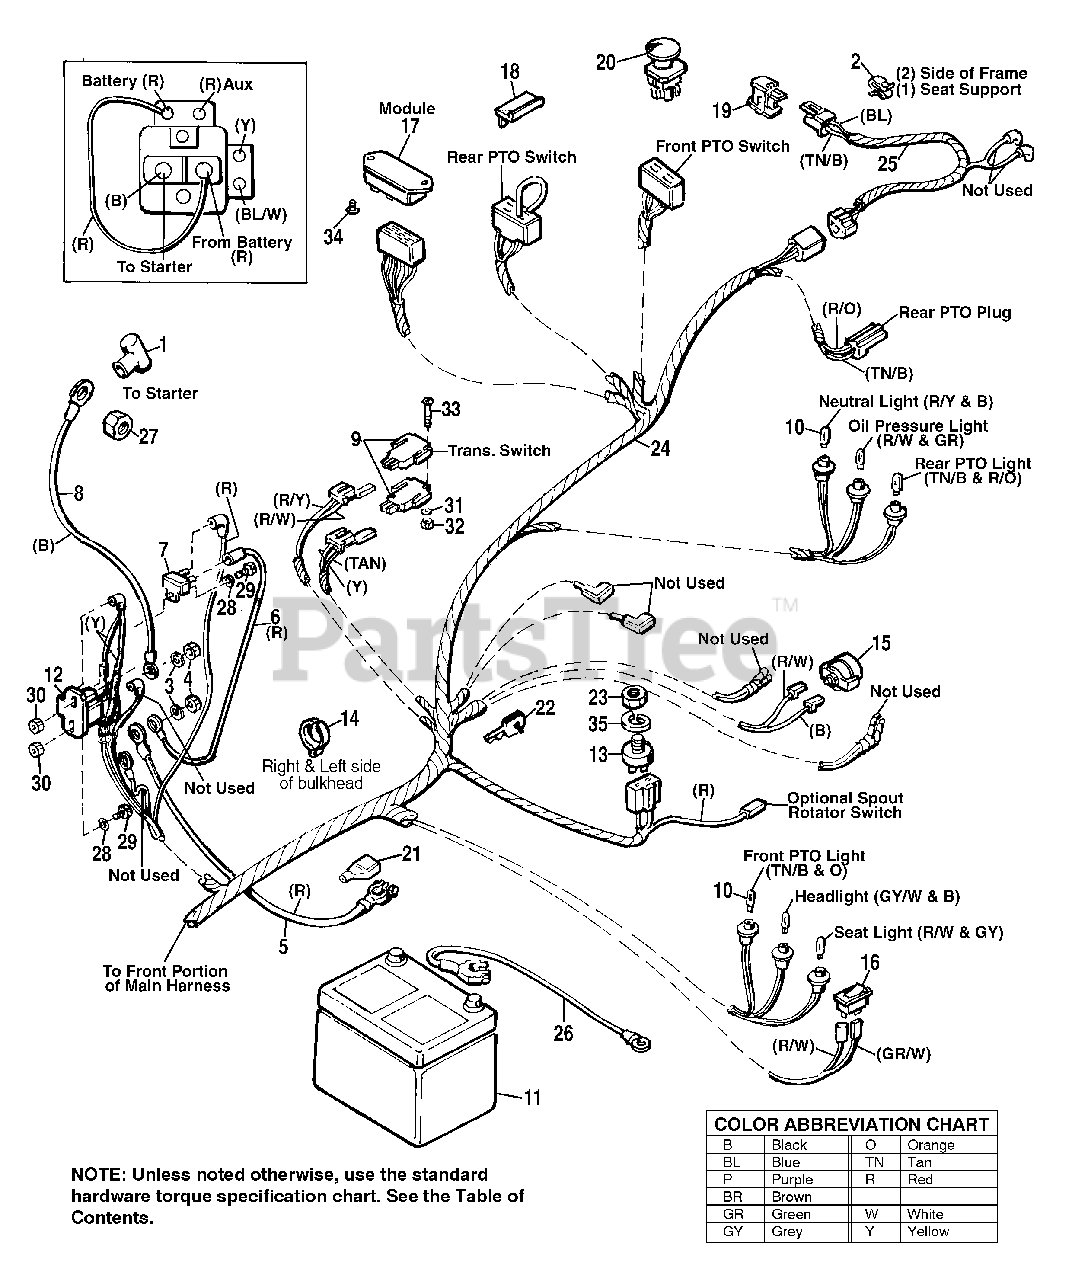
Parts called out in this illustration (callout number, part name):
1	COVER, Terminal
2	CLIP, Tinnerman
3	WASHER, 5/16, Zinc Plated
4	NUT, Hex, Jam, 5/16-24 Zinc Plated
5	CABLE (Battery to Solenoid)
6	WIRE, Solenoid to Circuit Breaker
7	BREAKER, Circuit
8	CABLE, Solenoid to Starter
9	SWITCH, Interlock (Under Dash) Shift Lever
10	LAMP, Indicator
11	BATTERY (400 AMP Cold Crank Rating)
12	SOLENOID (12 Volt DC)
13	IGNITION SWITCH KIT,
16	TOGGLE SWITCH, Headlight
17	INTERLOCK MODULE
19	SAFETY SWITCH (Seat), Operator Present
20	SWITCH ASSY., PTO
21	PROTECTOR, Battery (Red)
22	IGNITION KEY
23	NUT, Hex, Flange, 5/8
24	WIRING HARNESS (Main)
25	HARNESS, Rear
26	CABLE (Battery to Ground)
27	NUT, Hex, 1/4-20
28	WASHER, Plain, 1/4
29	CAPSCREW, Hex Hd., 1/4-20 x 3/4
30	NUT, Hex, Flange, Whizlock, 1/4-20
31	LOCKWASHER, #5
32	NUT, Hex, #5-40
33	SCREW, #5-24 x 1-1/2
34	SCREW, Hex, Washer Hd., Plastite, #8-16 x 1/2
35	WASHER, Internal Tooth, 5/8
